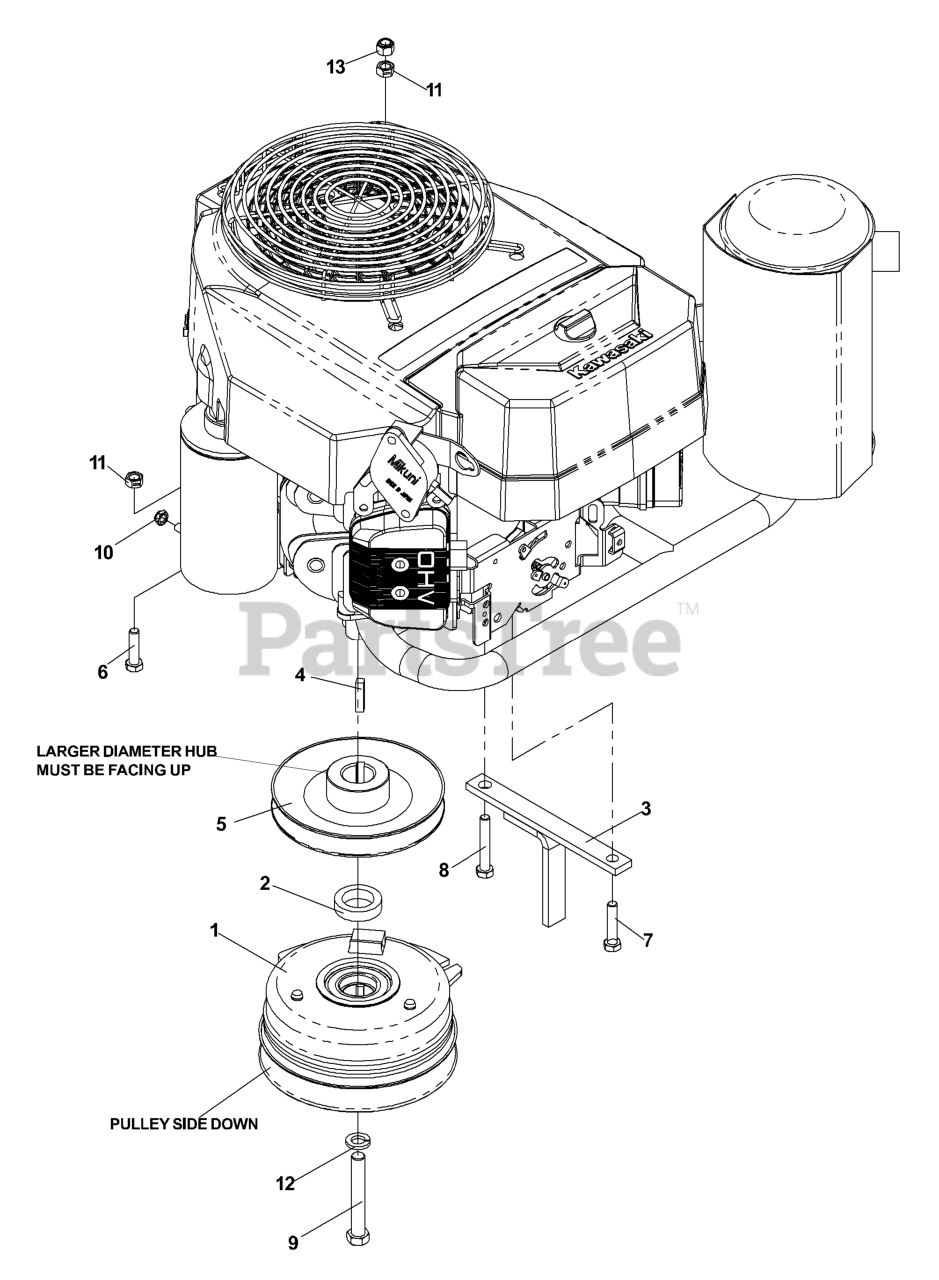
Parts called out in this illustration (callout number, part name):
1	CLUTCH 125 FT/LB
3	CLUTCH TIE DOWN
4	KEY 1/4 SQ X 1 1/8
6	HCS 5/16C X 1 1/4
7	CAPSCREW 5/16 X 1/1/2 HEX HEAD
8	HCS 5/16-18X2
9	HEX SCREW 7/16-20 X 3
10	JAM NUT 1/4C (2 2 PW01)
11	NUT 5/16C CENTERLOCK
12	WASHER 7/16 LOCK
13	NUT 5/16 NYLOC
